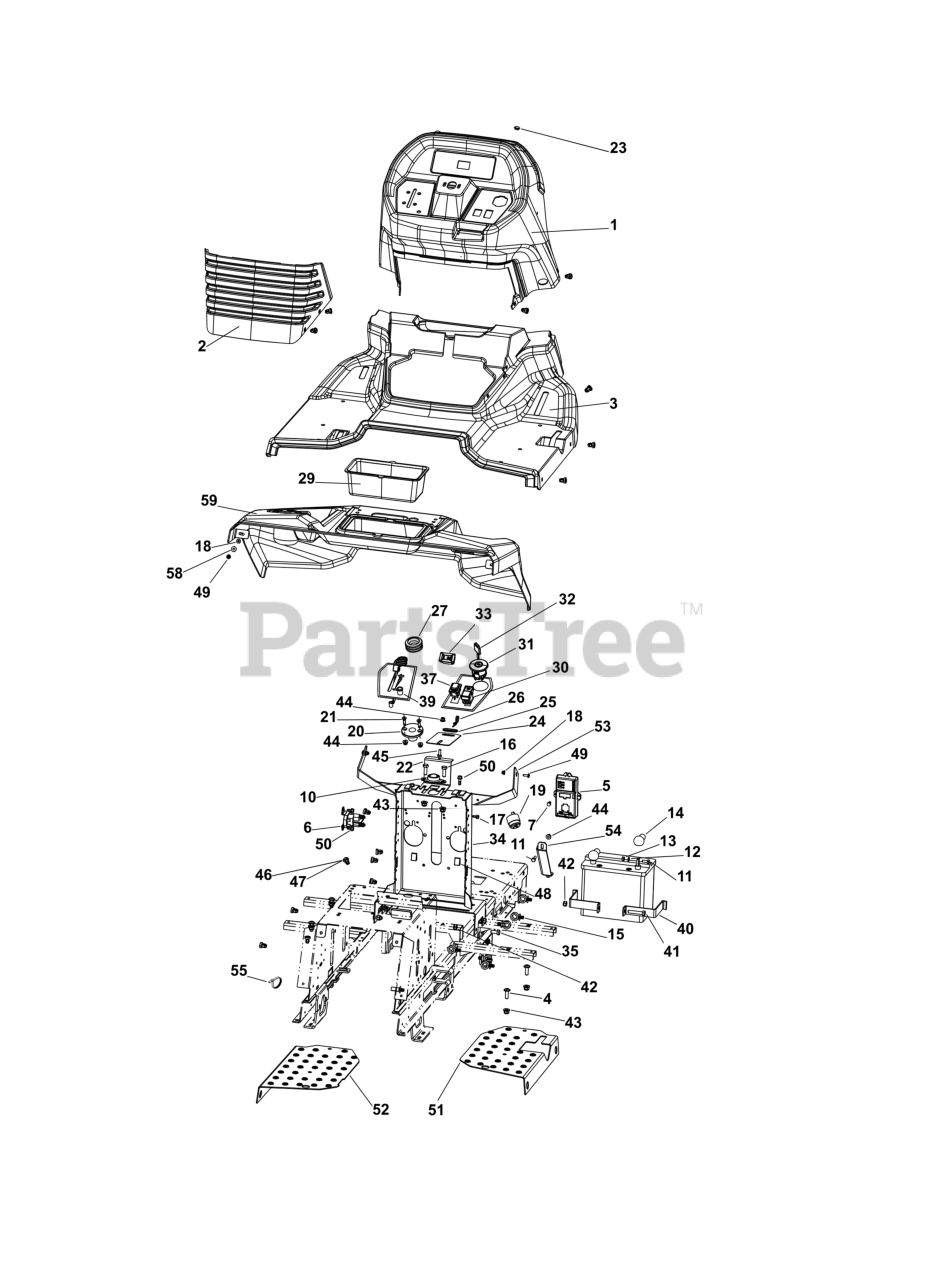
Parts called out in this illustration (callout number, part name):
1	PANEL, Dashboard
2	COVER, Battery
3	DASHBOARD
6	SOLENOID
23	DAMPER, Rubber
32	KEY, Ignition
33	HOURMETER
39	LIGHT, Indicator
51	PLATE, Reinforcement
52	PLATE, Reinforcement
59	SEAT DECK
